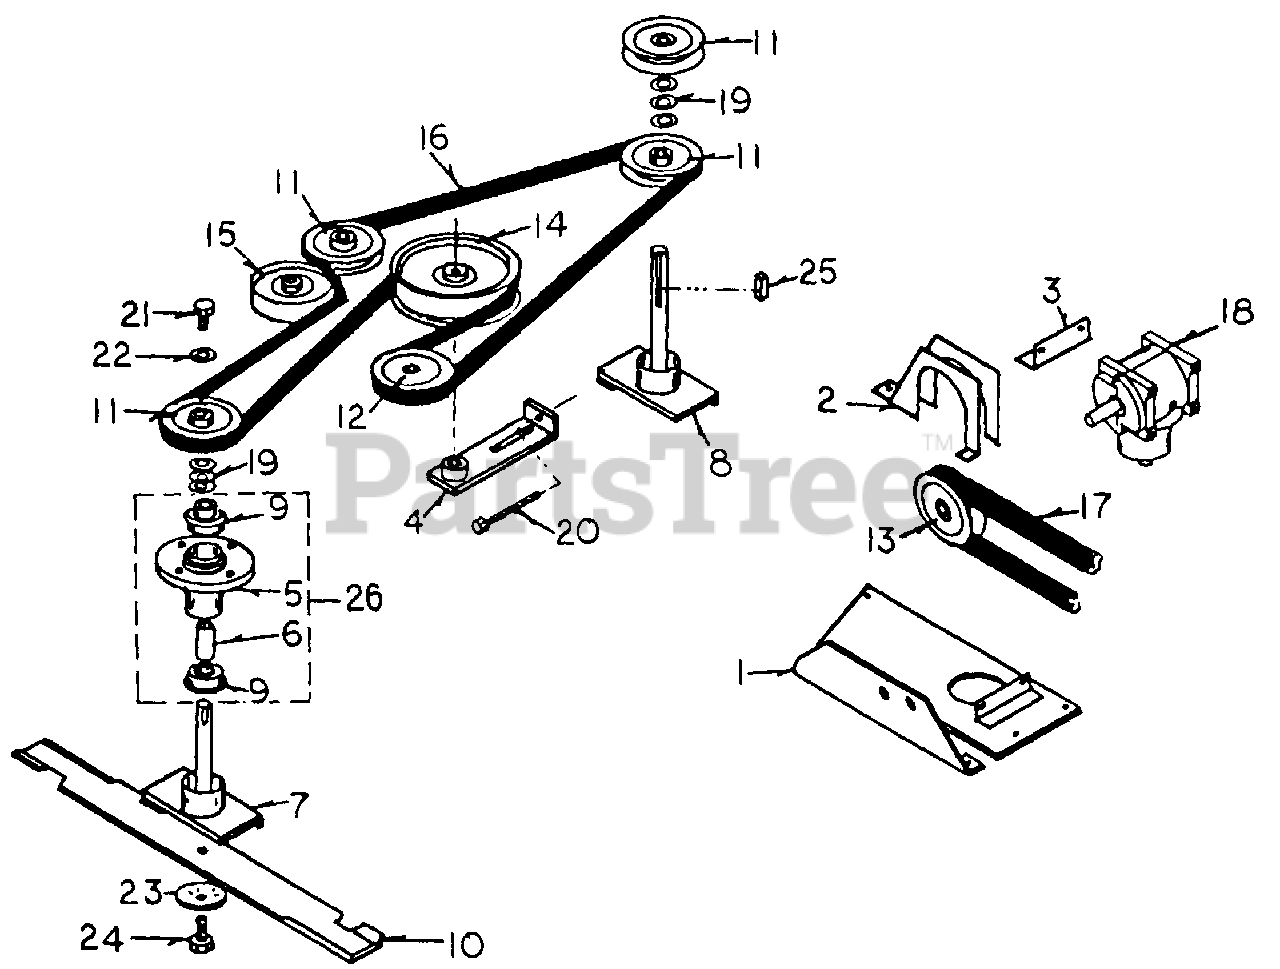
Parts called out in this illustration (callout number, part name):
1	Gearbox, Mount
2	Belt Guard
3	Gearbox Mount Angle
4	Belt Tightener
5	Spindle Housing
6	Spindle Spacer
7	Spindle Shaft
8	Spindle Shaft, Long
9	Spindle Bearing
11	Spindle Pulley
12	Gearbox Pulley, Output
13	Gearbox Pulley, Input
14	Idler Pulley, Large
15	Idler Pulley, Small
17	Deck Drive Belt
20	Adjustment Bolt
21	Hex Ny-Lock Bolt, 5/16-24 x 3/4"
22	Washer, 5/16", 10 GA
24	Hex Bolt, 3/8-24 x 1 1/4"
25	Key Stock, 3/16"
26	Spindle Housing Assembly
